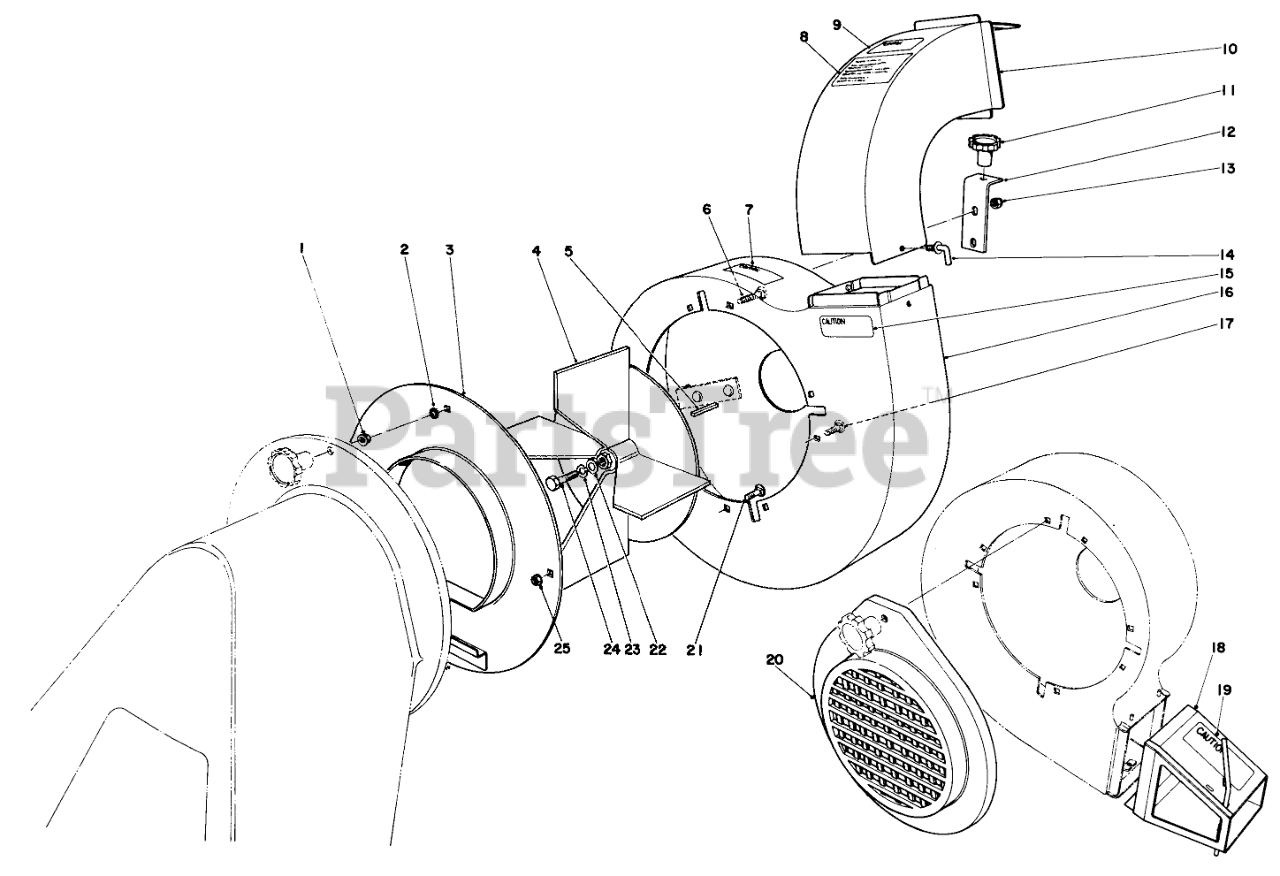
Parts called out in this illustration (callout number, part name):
1	NUT-FLANGE
2	WASHER-LOCK
3	Blower Cover
4	Fan
5	KEY-SQUARE
6	BOLT-CARR
7	Decal-Caution
8	TORO ADVER DECAL
9	DECAL CAUTION BAG
10	Chute-Vacuum
12	Mounting Bracket
13	NUT-LOCK, CONE
14	ADJ SCREW 1/4-20X 3/4
15	WARNING DECAL
16	Blower Housing
17	SCREW-CARR
18	EXHAUST BLOWR WA/DECAL
19	EXHAUST DECAL
20	INTAKE-BLOWER
21	SCREW-CARR
22	WASHER-FLAT
23	WASHER-LOCK
24	Capscrew
25	NUT-KEPS
